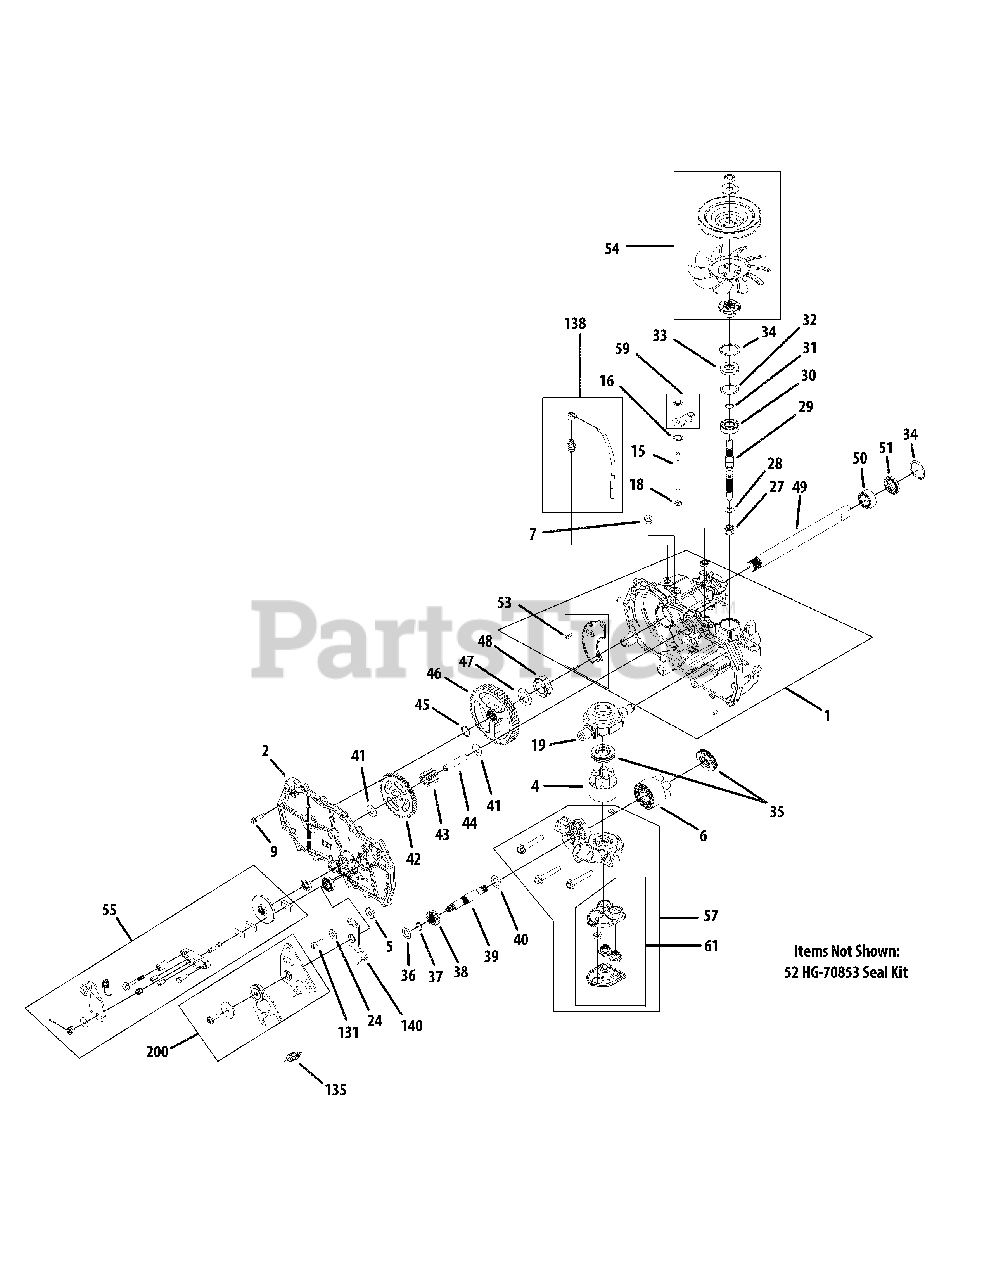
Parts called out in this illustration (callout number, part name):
1	Kit, Housing, Main, LH
2	Kit, Housing, Side, LH
4	Kit, Block, 7 Piston
5	Spacer, .320 x 1.005 x .150
6	Kit, Block, 10cc Cylinder
9	Screw, Hex Washer
15	Rod, Bypass
16	Ring, Ret .375 External
18	Ring, Retaining .375 External
19	Trunnion, Swashplate
24	Washer, .34 x .88 x .06
27	Spring, Block
28	Washer, .59 x .79 x .04
29	Shaft, Input
30	Ball Bearing 17 x 40 x 12
31	Ring, Reatining
32	Washer, 1.23 x 1.57 x .04
33	Seal, Lip 17 x 40 x 7
34	Ring Retaining Internal
35	Thrust Bearing, 30 x 52 x 13
36	Washer, .63 x 1.00 x .05
37	Ring, Reatining, Motor Shaft
38	Gear, 13T Pinion
39	Shaft, Motor
40	Washer, .71 x 1.16 x .04
42	Gear, 10T/48T
43	Gear, 10T Jackshaft
44	Pin, Jackshaft
45	Ring, Spiral Retaining-87
46	Gear, Bull 52T
47	Washer, 1.018 x 1.571 x .105
48	Buahing, Sleeve (Inboard)
49	Shaft, Axle, 1.00 x 11.70 DD
50	Bushing, 1.003 x 1.571 x .625
51	Seal, Lip, TC4, 1.00 x 1.577 x .27
52	Kit, Seals & Rings
53	Kit, Expansion Plate LH
54	Kit, Fan & Pulley
55	Kit, Brake Arm
57	Kit, Center Section LH
59	Kit, Bypass Arm
61	Kit, Filter
131	Socket Cap Screw, 5/16-24 x 7/8
135	Spring, Extension
138	Kit, Breather
140	Arm, Left Return
200	Kit, RTN Bidirectional
